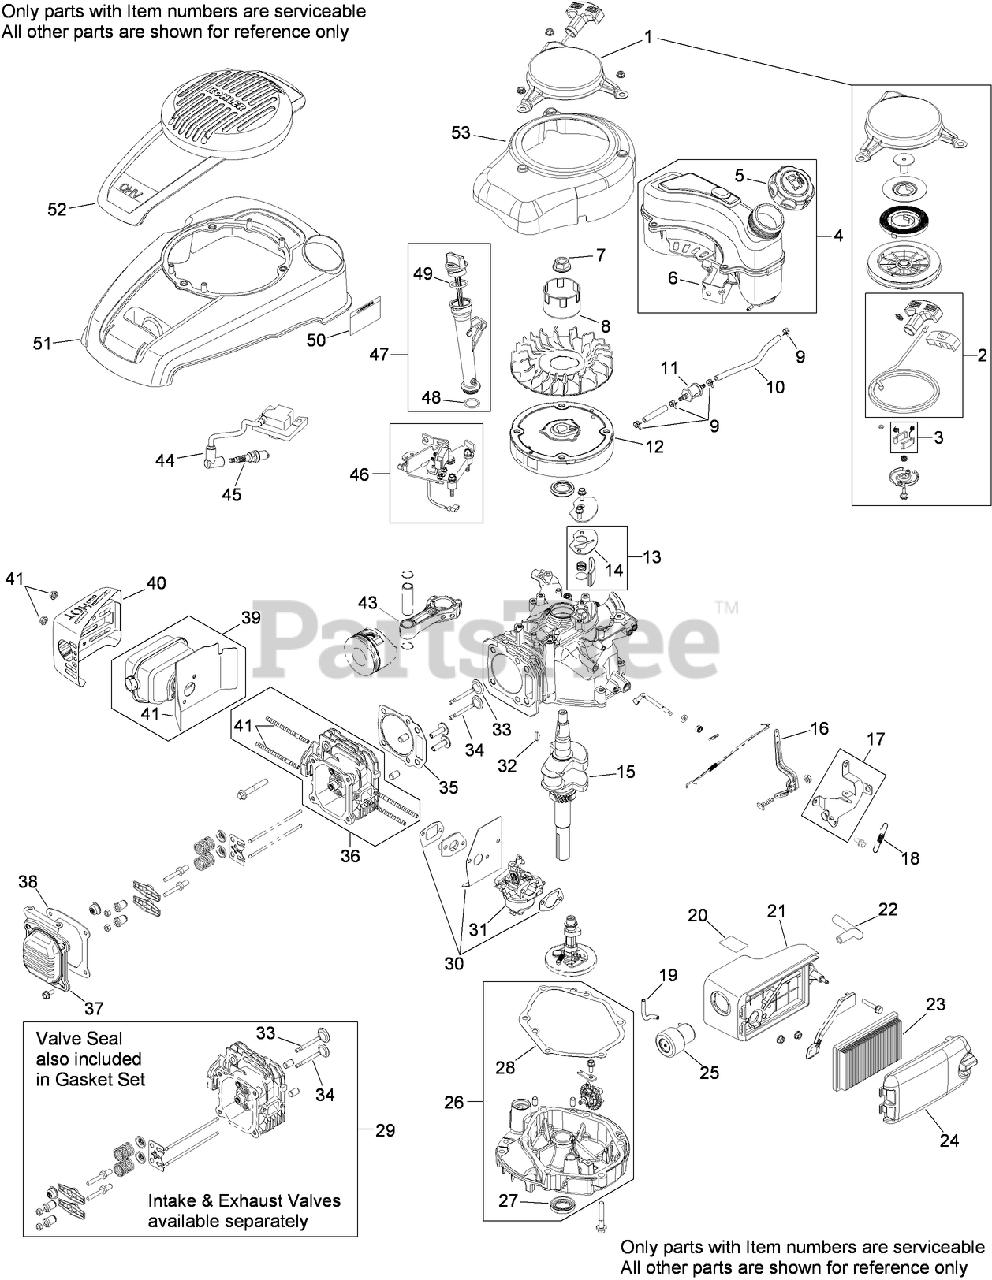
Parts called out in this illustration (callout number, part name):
1	STARTER-RECOIL (INCLUDES 2, 3, RECOIL HOUSING, BUSHING, GUIDE PLATE, SPRINGS, PULLEY, RETAINER PLATE, SHOULDER SCREW)
2	STARTER ROPE W/ HANDLE KIT (INCLUDES COIL STARTER ROPE, RECOIL STARTER HANDLE, STARTER HANDLE RETAINER, ROPE RETAINER)
3	PAWL REPAIR KIT (INCLUDES RECOIL SPRING, STARTER PAWL)
4	FUEL TANK KIT (INCLUDES 5, 6)
5	FUEL CAP ASM
6	BRACKET-TANK, FUEL (LOWER)
7	NUT-FLYWHEEL
8	CUP-DRIVE
9	CLAMP-LINE, FUEL
10	LINE-FUEL (10-CUT TO LENGTH)
11	Filter-Fuel
12	FLYWHEEL (ALUMINUM)
13	BREATHER FILTER KIT (INCLUDES 14, BREATHER COVER SPRING, FILTER, REED)
14	GASKET-COVER, BREATHER
15	CRANKSHAFT ASM
16	LEVER-GOVERNOR
17	BRACKET-CONTROL (FIXED SPEED)
18	SPRING-GOVERNOR (2800-3300 RPM)
19	HOSE-PRIMER
20	DECAL-PRIMER
21	AIR CLEANER BASE KIT (PRIMER) (INCLUDES AIR CLEANER BASE GASKET)
22	TUBE-BREATHER
23	ELEMENT-CLEANER, AIR
24	COVER-CLEANER, AIR
25	PRIMER ASM KIT (EVAP) (INCLUDES AIR CLEANER BASE GASKET)
26	OIL PAN KIT
27	SEAL-OIL (PTO)
28	GASKET-PAN, OIL
29	VALVE TRAIN KIT (INCLUDES 33, 34, VALVE SPRING RETAINER, STEM SEAL, ROCKER ARM STUD, VALVE SPRING, JAM NUT, PUSHROD GUIDE PLATE, ROCKER ARM, CYLINDER HEAD DOWEL, PUSH ROD, ROCKER ARM PIVOT)
30	CARBURETOR GASKET KIT (INCLUDES CARBURETOR HEAT SHIELD GASKET, SPACER GASKET, AIR CLEANER BASE GASKET)
31	CARBURETOR KIT (PRIMER) W/GASKETS (INCLUDES 30)
32	KEY-FLYWHEEL
33	VALVE-INTAKE
34	VALVE-EXHAUST
35	HEAD GASKET KIT (INCLUDES 30, MUFFLER GASKET)
36	CYLINDER HEAD KIT (INCLUDES CARBURETOR STUD, EXHAUST STUD)
37	VALVE COVER KIT (INCLUDES 38)
38	GASKET-COVER, VALVE
39	MUFFLER KIT (INCLUDES MUFFLER GASKET)
40	SHIELD-MUFFLER
41	EXHAUST HARDWARE KIT (INCLUDES MUFFLER GASKET, EXHAUST STUD AND FLANGE LOCK NUT)
43	ROD-CONNECTING
44	MODULE-IGNITION (ALUM STD IGN)
45	SPARK PLUG (K 5 R T C)
46	FLYWHEEL BRAKE KIT (INCLUDES BRAKE LEVER, BRAKE SPRING, FLANGE NUTS, BRAKE PAD, GROUND TO KILL LEADS, SCREWS, SWITCH INSULATORS, BRAKE SWITCH CONTACT, BRAKE SPACER, BRAKE BRACKET, FLANGE SCREW, BRAKE LEVER SCREW, NYLON FLATWASHER)
47	DIPSTICK AND TUBE KIT (INCLUDES 48, 49)
48	O RING-FILL TUBE, OIL
49	O RING-DIPSTICK
50	DECAL-WARNING
51	COVER-ENGINE (BLACK)
52	INSERT-COVER, ENGINE (LOW PROFILE)
53	HOUSING-BLOWER
